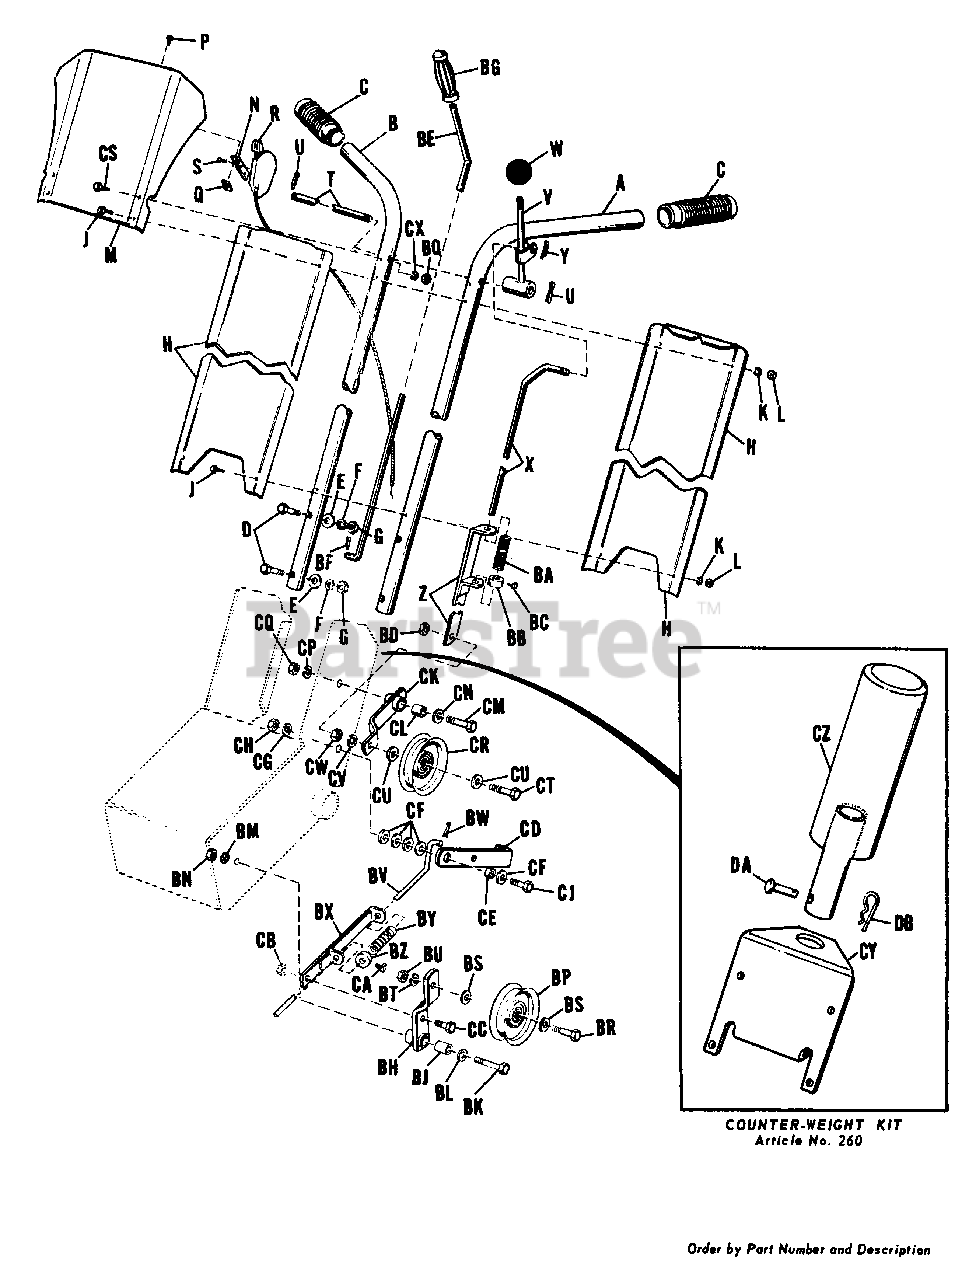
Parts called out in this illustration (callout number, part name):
A	Handled, LH
B	Handled, RH
D	Hex Capscrew, 3/8"-16 x 2"
E	Washer, Plain, 3/8"
F	Lock Washer, 3/8"
G	Hex Nut, Full, 3/8"-16
H	Handle Cover
J	Hex Capscrew, 1/4-20 x 1-1/2
K	Lock Washer, 1/4"
L	Hex Nut, Full, 1/4"-20
M	Housing Assembly
N	Support, Throttle Control
P	Hex Screw, self-tap. #10-32 x 1/2
Q	Speed Nut, Tinnerman
R	Throttle Control Assembly
S	Screw, self-Tap. #10-24 x 1/2
T	Lever Pin
U	Cotter Pin, 3/32" x 3/4" lg.
V	Lever Assembly, LH
X	Transmission Clutch Rod
Y	Cotter Pin, 3/32" x 3/4" lg.
Z	Idler Clutch Rod Guide Assy.
BC	Set Screw,Rd.Hd. 1/4-20 x 3/8
BD	Hex Nut, Full, Lock, 3/8"-16
BE	Reverse Rod
BF	Cotter Pin, 3/32" x 3/4"
BG	Grip, Reverse Rod
BH	Idler Lever Assembly
BJ	Bearing Race, Inner
BK	Hex Capscrew, 3/8-16 x 1-3/4
BL	Plain Washer, 3/8"
BM	Lock Washer, 3/8"
BN	Hex Nut, Full, 3/8"-16
BP	Idler Pulley (Rotor Drive)
BQ	Hex Nut, Full, 1/4"-20
BR	Hex Capscrew, 3/8-16 x 1-3/4
BS	Plain Washer, 3/8"
BT	Lock Washer, 3/8"
BU	Hex Nut, Full, 3/8"-16
BV	Rotor Clutch Rod
BW	Cotter Pin, 3/32" x 3/4" lg.
BX	Clutch Rod Guide Assembly
CA	Set Screw, Sq. Hd, 1/4-20 x 3/8
CB	Hex Nut Full, Lock, 3/8"-16
CC	Hex Capscrew 3/8"-16 x 3/4
CD	Foot Clutch Pedal
CF	Plain Washer, 3/8"
CG	Lock Washer, 3/8"
CH	Hex Nut, Full, 3/8"-16
CJ	Hex Capscrew, 3/8-16 x 1-1/2
CK	Idler Lever Assembly
CL	Race, Inner Bearing
CM	Hex Capscrew, 3/8-16 x 1-3/4
CN	Plain Washer, 3/8"
CP	Lock Washer, 3/8"
CQ	Hex Nut, Full, 3/8"-16
CR	Idler Pulley (Trans. Drive)
CS	Hex Capscrew, 1/4-20 x 1-3/4
CT	Hex Capscrew, 3/8"-16 x 2"
CU	Plain Washer, 3/8"
CV	Lock Washer, 3/8"
CW	Hex Nut, Full, 3/8"-16
CX	Lock Washer, 1/4"
